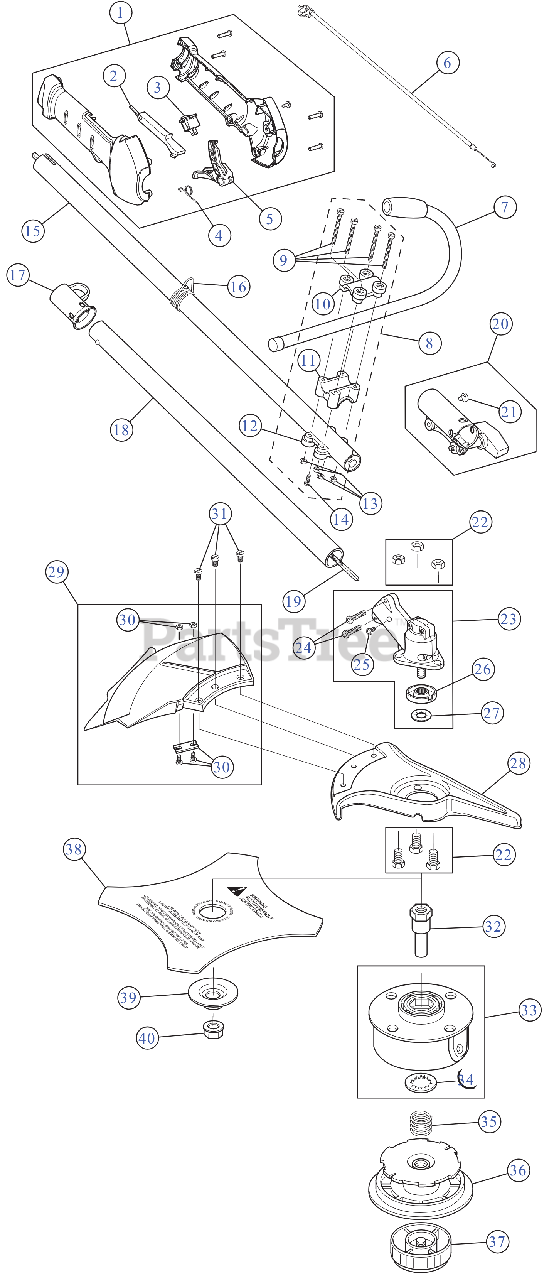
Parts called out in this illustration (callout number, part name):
1	THROTTLE GRIP ASSEMBLY
2	LEVER LOCK OUT
3	SW, MOMENTARY ON/O
4	SPRING TRIG
5	THROTTLE TRIGGER
6	THROTTLE CABLE
7	HANDLE ASSEMBLY-JAY
8	HANDLE BRACKET ASSEMBLY
9	CLAMP SCREW
10	HANDLE UPPER CLAMP
11	HANDLE MIDDLE CLAMP
12	HANDLE LOWER CLAMP
14	SCREW, 8-32 x .312 P
15	BOOM ASSEMBLY UPR
16	CLAMP-SHOULDER STR
18	ASSEMBLY, LOWER DRIVE S
19	LOWERIBLE DRIVE SHAFT
20	SPLIT BOOM COUPLER KIT
21	SCREW, 10-32X.250 TA
22	SCREW SET-GUARD MT
23	GEARBOX ASSEMBLY
25	SCREW, 8-32 x .312 P
26	SPACER-GEARBOX
27	PALNUT:3/8" DIAM
28	SHIELD-BLADE CAST
29	SHIELD ASSEMBLY WITH BLADE
30	BLADE ASSEMBLY
31	SCREW-GUARD MTG PK
32	SHAFT-SPOOL
33	SPOOL ASSEMBLY-OUTER
34	RETAINER .968 OD
35	SPRING-SPOOL
36	REEL-INNER SPOOL 3000 STRG TRM
37	KNOB ASSEMBLY-BUMP 3000 STRG TRM
38	BLADE 4-TOOTH
39	WASHER-BLADE CLAMP BRUSH CUT
40	BLADE LOCK NUT
